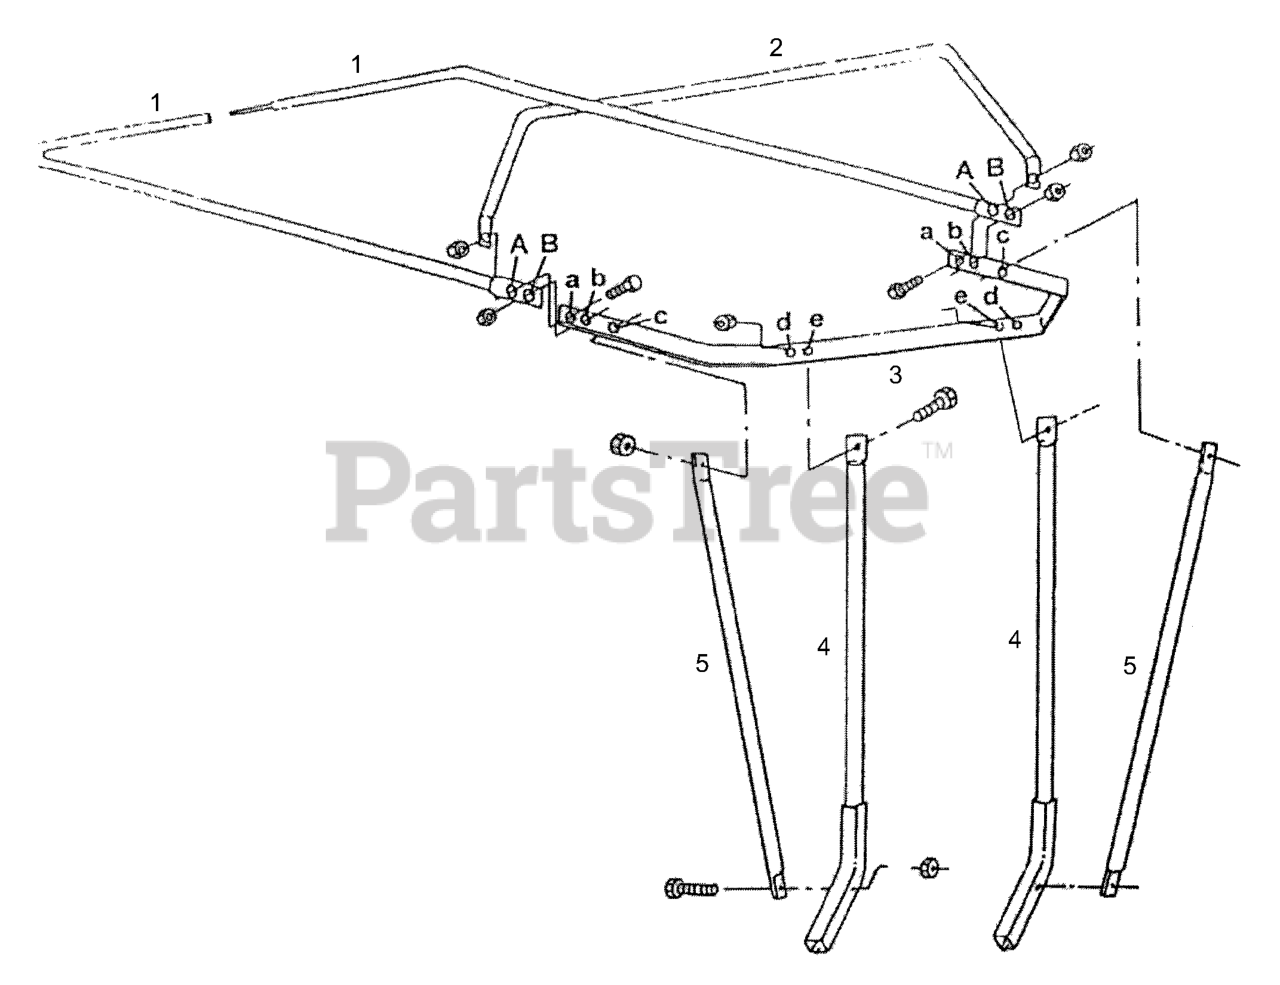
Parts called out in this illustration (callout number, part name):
1	BOW, FRONT (Tapered end)
1	BOW, FRONT
2	BOW, TOP
3	BOW, REAR
4	POST
5	BRACE
A	RECEIVER, RH
B	RECEIVER, LH
C	CROSS BAR(Flat Fender LT Tractor ONLY)
